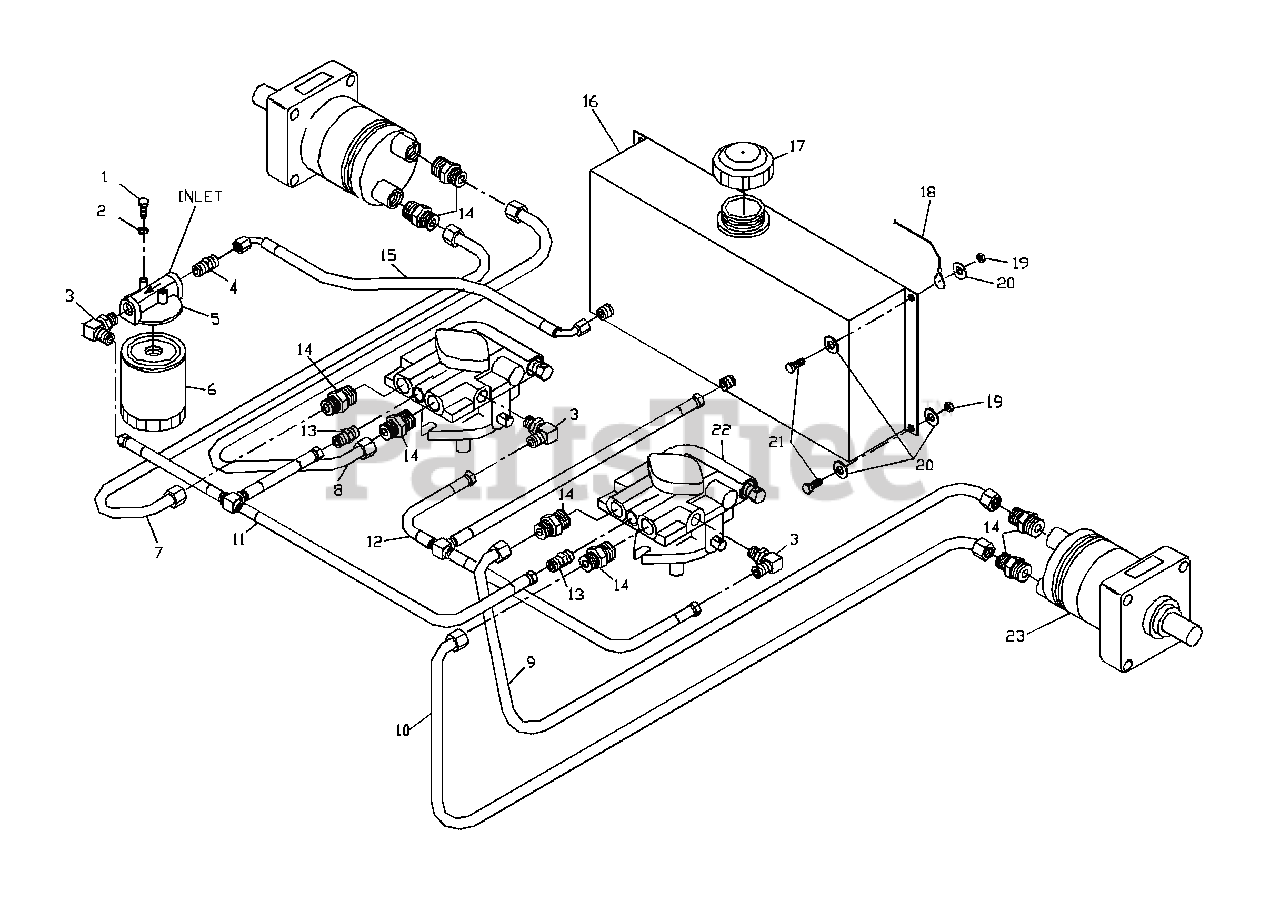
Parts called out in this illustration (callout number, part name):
1	HCS 1/4C X 5/8
2	1/4" LOCKWASHER
3	F6801-6-6-0 90 DEG. ELBOW
4	F6400-6-6-0 STRAIGHT FITTING
5	FILTER HEAD
7	RIGHT OUTSIDE TUBE
8	RIGHT INSIDE TUBE
9	LEFT INSIDE TUBE
10	LEFT OUTSIDE TUBE
11	SUCTION TEE ASSEMBLY
12	RETURN TEE ASSEMBLY
13	F6400-6-4-0 STRAIGHT FITTING
14	F6400-8-8-0 STRAIGHT FITTING
16	TANK, HYDRAULIC
17	HYDRAULIC CAP
18	SEAT LANYARD
19	NUT 1/4C CENTERLOCK
20	WASHER 1/4 FLAT
21	HCS 1/4C X 1
23	WHEEL MOTOR
